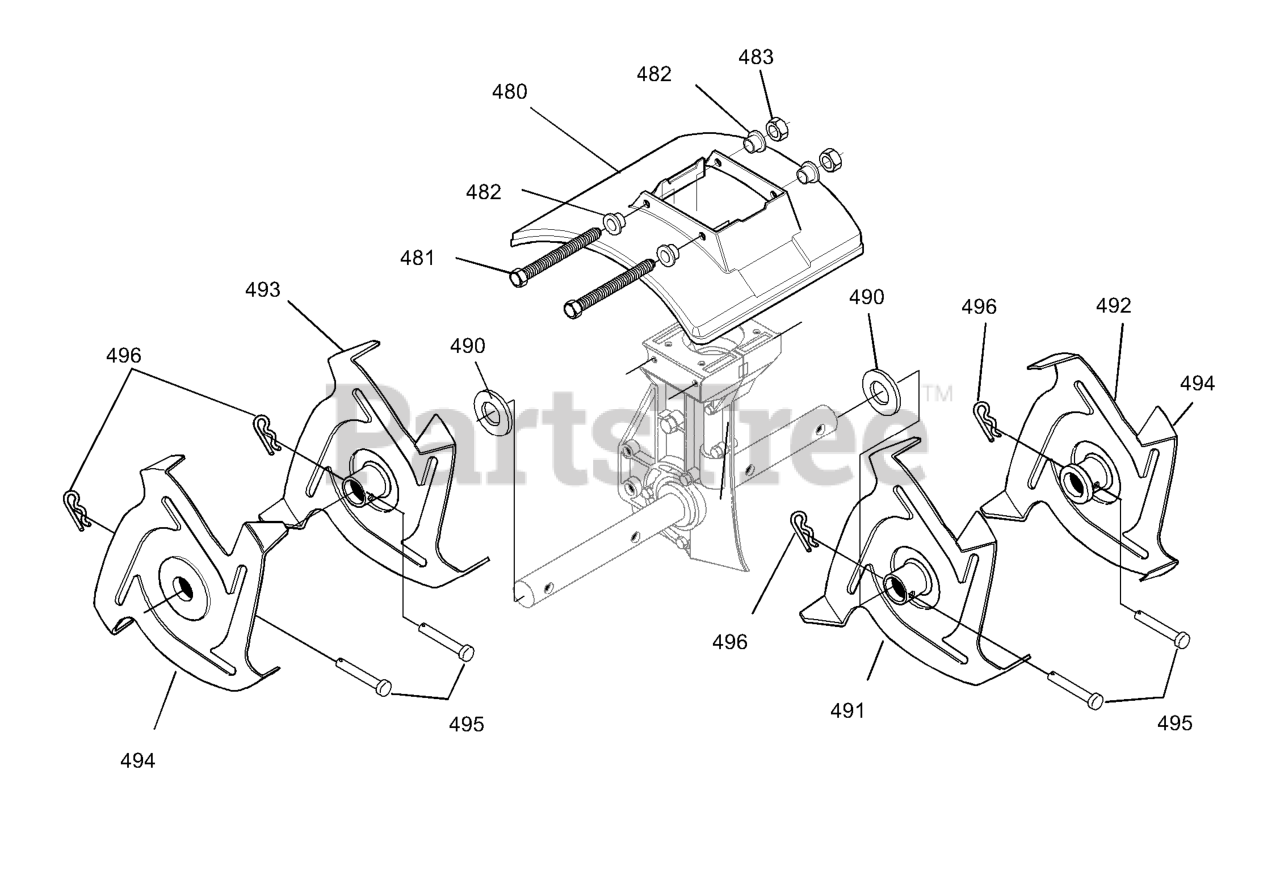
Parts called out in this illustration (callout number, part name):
480	Shield, Tine
481	Screw, 1/4-20x5.50
482	Spacer, Flange
483	Nut, 1/4-20
490	Washer, Felt
491	Tine Assy. Inner LH
492	Tine Assy. Outer LH
493	Tine Assy. Inner RH
494	Tine Assy. Outer RH
495	Clevis Pin
496	Hair Pin
